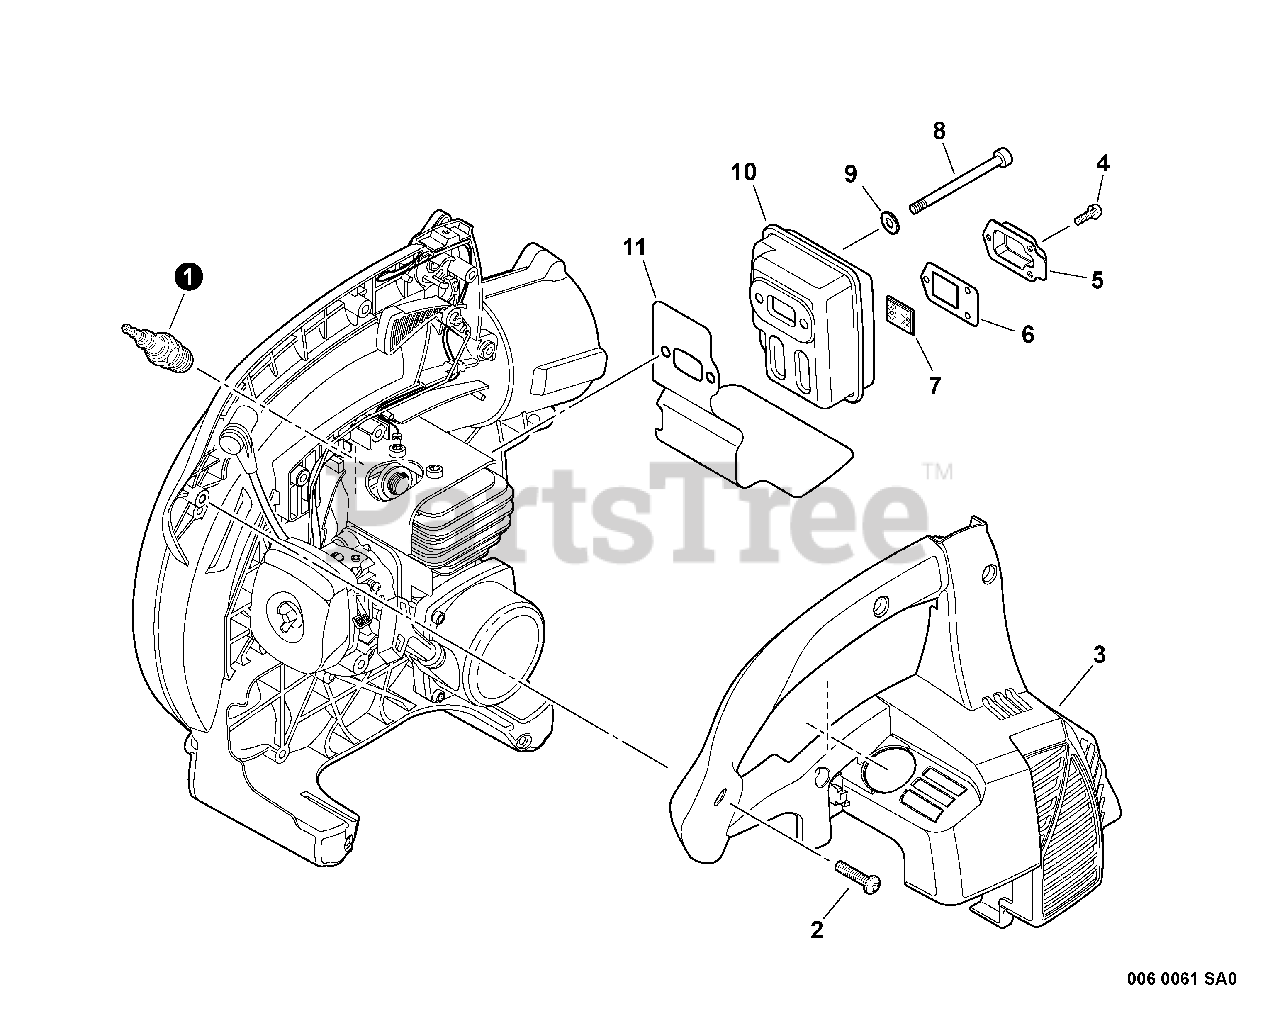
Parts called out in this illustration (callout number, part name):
1	SPARK PLUG - BPM8Y
2	BOLT, TORX 5×20
3	COVER, ENGINE
4	SCREW 4×10
5	GUIDE, EXHAUST
6	GASKET, EXHAUST
7	SCREEN, SPARK ARRESTER
8	BOLT 5×55
9	WASHER 5.5×12×0.8
11	HEAT SHIELD, EXHAUST
